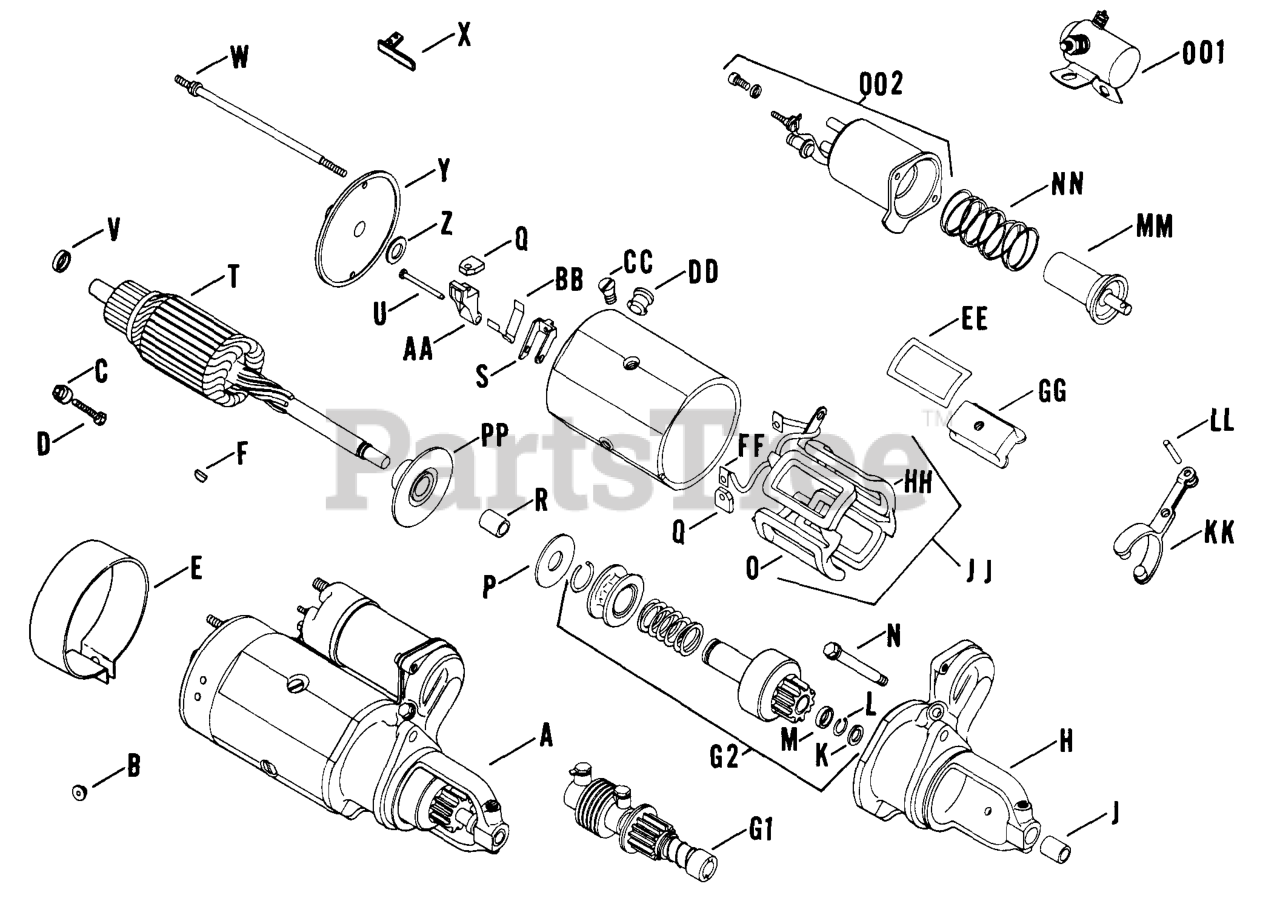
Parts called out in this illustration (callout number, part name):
A	STARTER - DISCONTINUED
G2	DRIVE - DISCONTINUED
H	HOUSING - DISCONTINUED
K	Collar, thrust
M	Collar, stop
N	Stud, lever
R	Bushing, center bearing
Y	FRAME - DISCONTINUED
CC	SCREW - DISCONTINUED
DD	Grommet, field frame
FF	Lead, brush ground
GG	Shoe, pole
OO2	SWITCH - DISCONTINUED
